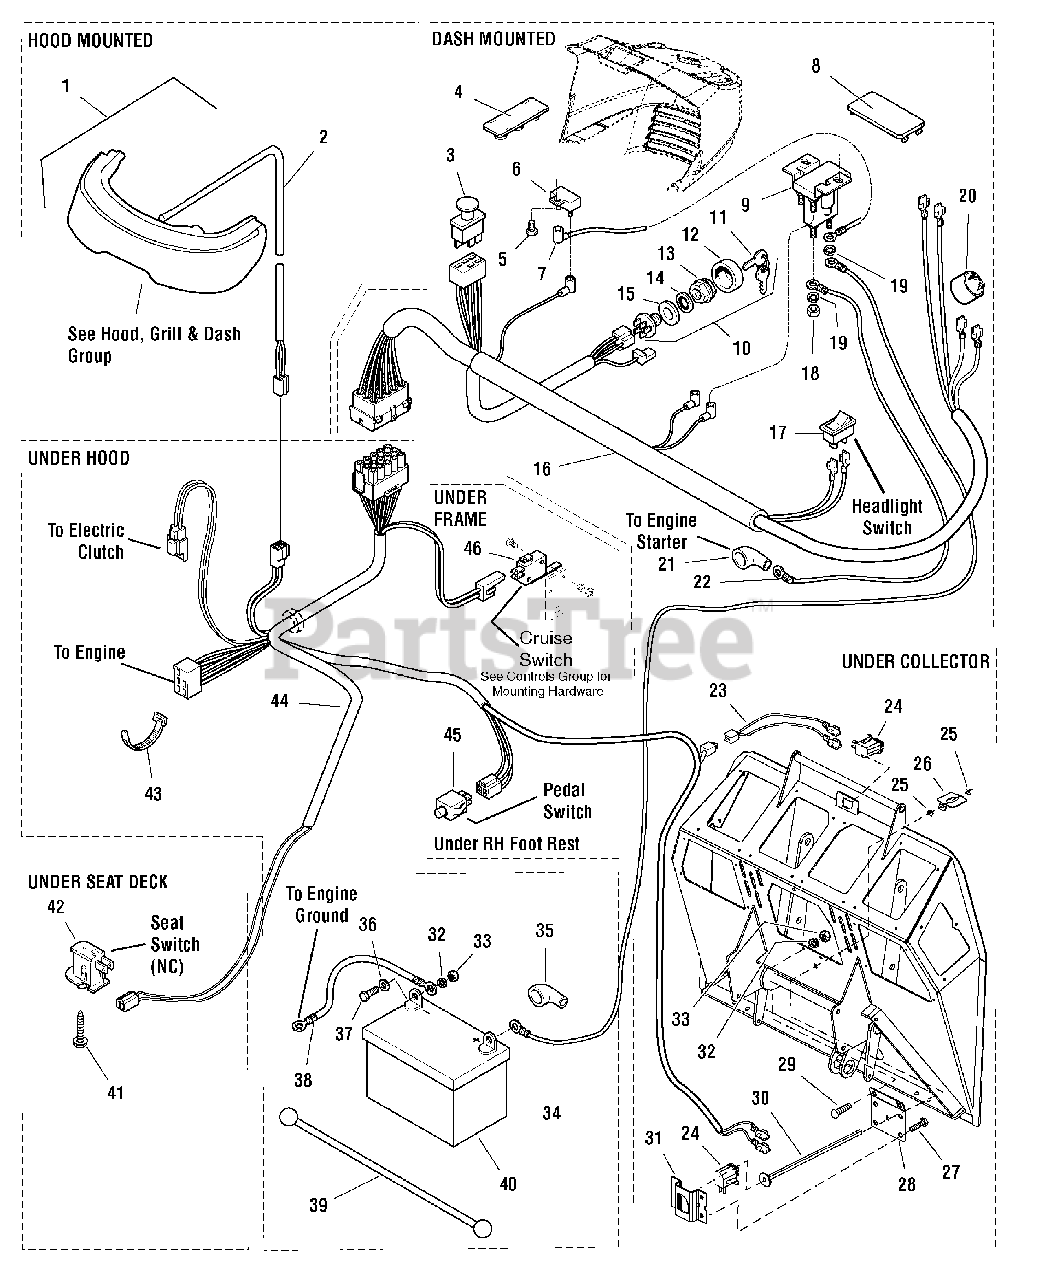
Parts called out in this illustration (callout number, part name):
1	HEADLIGHT ASSEMBLY
2	HARNESS, Headlight Assembly
3	SWITCH, PTO, Push/Pull
4	PLUG, Hole
5	CAPSCREW, Hex Head, 1/4 x 5/8
6	BREAKER, Circuit 12Volt, 20Amps
7	WIRE, 12GA, 5.9" Long, Red
8	PLUG, Dash, Early Models
8	PLUG, Dash, Later Models
9	SOLENOID
10	SWITCH ASMY, Ignition, 6 Pin, (Includes Ref. Nos. 11, 12, 13
11	KEY, Ignition
12	COVER
13	NUT, Hex Flange, 5/8-32
14	LOCKWASHER, Internal Tooth, 5/8
15	WASHER
16	HARNESS, Wiring Upper, Early Models
16	HARNESS, Wiring Upper, Later Models
17	SWITCH, Headlights , 2 Terminal
18	NUT, Hex, 5/16-24
19	LOCKWASHER, External Tooth, 5/16
20	BUZZER, Pulse, Bag Full
21	BOOT, Insulator
22	CABLE, # 6, 25" Long, Red
23	HARNESS, Rear
24	SWITCH, Push Button, Black
25	O- RING
26	PAD, Acuator
27	CAPSCREW, Hex Head Taptite, 1/4-20 x 1/2
28	BRACKET, Switch
29	CARRIAGE BOLT1/4-20 x 5/8
30	ROD & WASHER ASSEMBLY, Hopper
31	BRACKET, Hopper Switch
32	LOCKWASHER
33	NUT, Hex, 1/4-20
34	CABLE, # 6, 9" Long
35	BOOT, Insulator Battery Terminal
36	WASHER
37	CAPSCREW, Hex Head, 1/4-20 x 3/4
38	CABLE, # 6, 26" Long
39	STRAP, Battery
40	BATTERY, 12Volt
41	SCREW, Hex Washer Head Plastite, 1/4-20
42	SWITCH, Operator Present, NC, Grey
43	TIE, Wire
44	HARNESS, Wiring Lower
45	SWITCH, Push Button Foot, Black
46	SWITCH, Cruise, Grey
